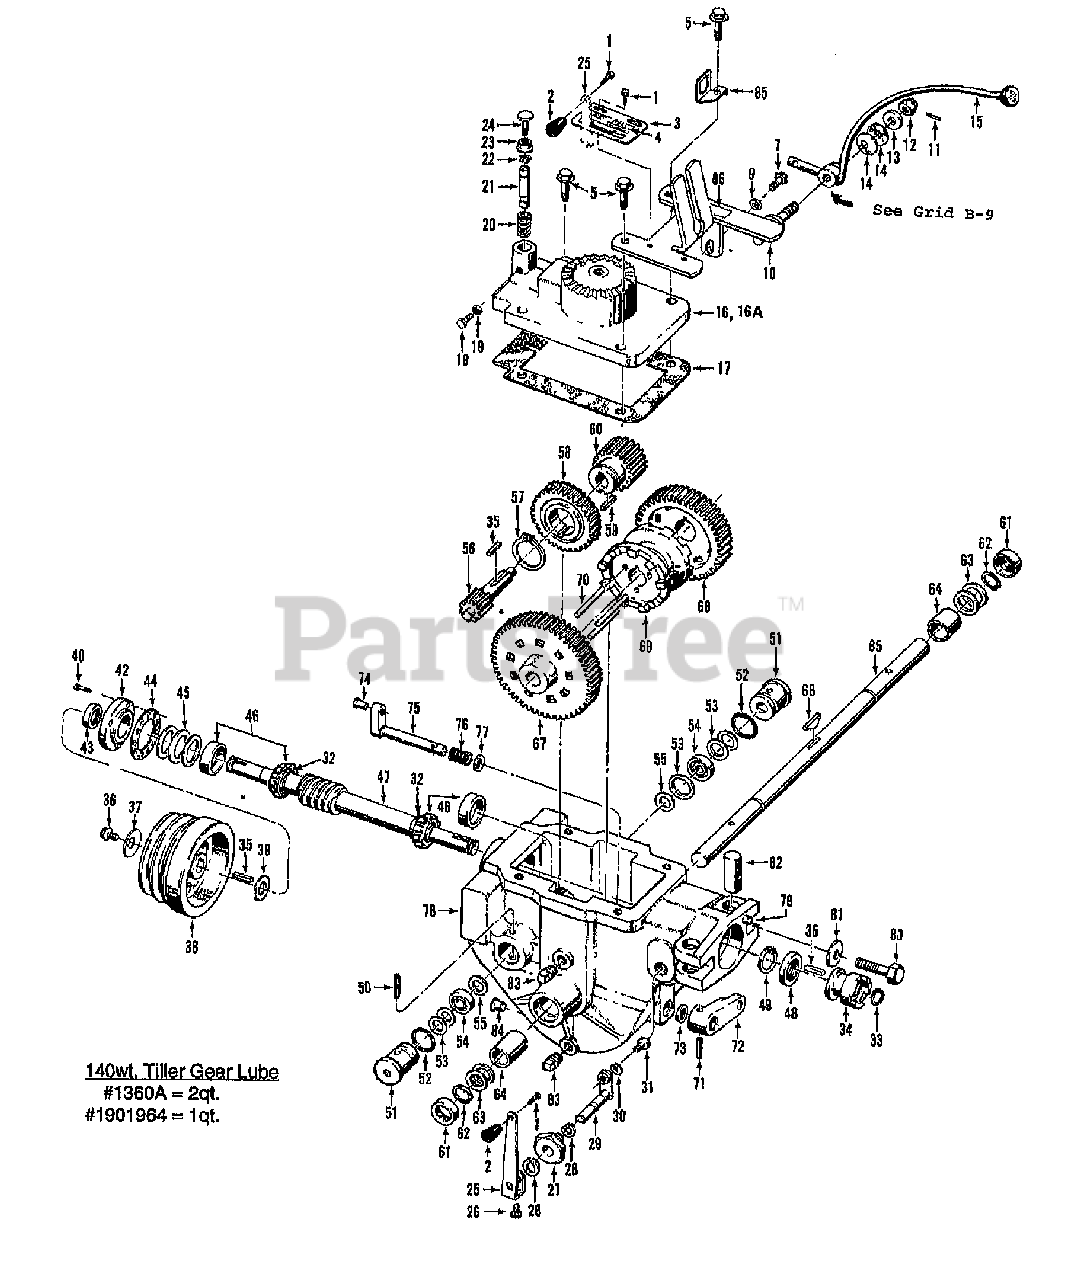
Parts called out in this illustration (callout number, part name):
1	SCR 10-32
2	KNOB-TAPERED
3	PLATE-TINE ENGAGE W/DECAL
4	DECAL-TINE ENGAGE
5	SCR-HFLK 3/8-16X1.50
6	THIS REF. NO. NOT USED
7	SCR-HFLK 5/16-18X.75 ZP
8	THIS REF. NO. NOT USED
9	WASHER-FLAT 5/16 SAE
10	BRKT-H HOOD 2149
11	PIN-SPRING .125 X 1
12	NUT-HEX 1/2-20
13	WASHER-# SHOULDER ZP
14	WASHER-# 1.97X1X.118
15	THIS REF. NO. NOT USED
16	COVER-TRANS RED 2523
16A	ASSM-TRANS COVER OPC
17	GASKET-TRANS COVER
18	SCR-HH 5/16-18X1.0 G5 ZP
19	NUT-HEX 5/16-18 ZP
20	SPRING-REV PLUNGER ZP
21	ASSM-NEUTRAL PLUNGER
22	RING-KLIP EXT .594 ID ZP
23	NUT-HFLK 3/8-16 ZP
24	SCR 3/8-16X1.5 UNC-2AG
25	LEVER-ECCENTRIC RED
26	SCR-HH 1/4-20X.5 GR5 YEL
27	BUSHING-.87X.5X.62 ECC
28	RING-RETAINING 5100-50
29	SHAFT-WELD ECCENTRIC
30	WASHER-LK .25 HI-COLLAR
31	SCR-HXSKT 1/4-20X.38 G8
32	SHIM-1.0X.7656X.062
33	RING-RETAIN EXT .707 ID
34	KIT-CLUTCH DOGS TILLER
34	CLUTCH-DOG HORSE TRANS
35	KEY-.188 SQX1.0
36	SCR-HH 5/16-24X.75 G5 ZP
37	WASHER-.827X.331X.098
38	PULLEY-TRANS MACH
39	WASHER-SHLDR HARDENED
40	SCR-HFLK 1/4-20X.75 G5 ZP
41	THIS REF. NO. NOT USED
42	COVER-FRONT
43	SEAL-PINION SHAFT PT/85030/00
44	GASKET-BRG COVER
45	SHIM-1.75X1.5X.01
45	SHIM-1.75X1.5X.03
45	SHIM-1.75X1.5X.005
45	SHIM-1.75X1.5X.062
46	KIT-BRG CONE&RACE-DRIVESHAFT
47	KIT-WHEELDRIVE ROLL/WORM
48	SEAL-OIL DRIVESHAFT
49	RING-RETAINING 5000-181
50	PIN-SPIROL .25 X 2.0
51	PLUG-PINION BRG W/RING
52	RING-O 1 ID
53	SHIM-1.234X1.015X.033
53	SHIM-1.234X1.015X.062
53	SHIM-1.234X1.015X.01
54	BRG-BALL (7 BALLS)
55	WASHER-# 1X.484X.06
56	GEAR-SPLINE 10 TEETH MACH
57	RING-RETAINING 5100-150
58	GEAR-WORM MACH
59	KEY
60	GEAR-SPUR 20 TEETH MACH
61	SEAL-OIL WHEELSHAFT
62	RING-HEAVY EXT .906 ID
63	SHIM-1.375X1.015X.062
63	SHIM-1.375X1.015X.03
63	SHIM-1.375X1.015X.015
63	SHIM-1.375X1.015X.01
63	SHIM-1.375X1.015X.005
64	BUSHING-1.25X1.005X1.5
65	KIT-WHEELSHAFT
66	KEY-HI PRO .25X1.812
67	GEAR-SPUR 56 TEETH MACH
68	GEAR-SPUR 46 TEETH MACH
69	CLUTCH-MACH
70	PIN-CLUTCH .25 2.65
71	PIN-SPIROL .188 X 1.25
72	LEVER-ECC. #1029
73	SEAL-OIL ECCENTRIC
74	PIN-.375 X .72
75	SHAFT-ECCENTRIC HORSE TLR
76	SPRING .845 X 1.25
77	WASHER # .875 X .65 X .06
78	CASE-TRANS W/PIN
79	PIN-DRIVE .375X.75 ZP
80	SCR-HH 1/2-13X2.0 G5 ZP
81	WASHER-DISC SPRING
82	POST (TC)
83	PLUG-PIPE 1/4 NPT
84	PLUG-CAP (RED)
85	CLIP-CONNECTOR
86	DECAL-FWD INTERLOCK WIRE
